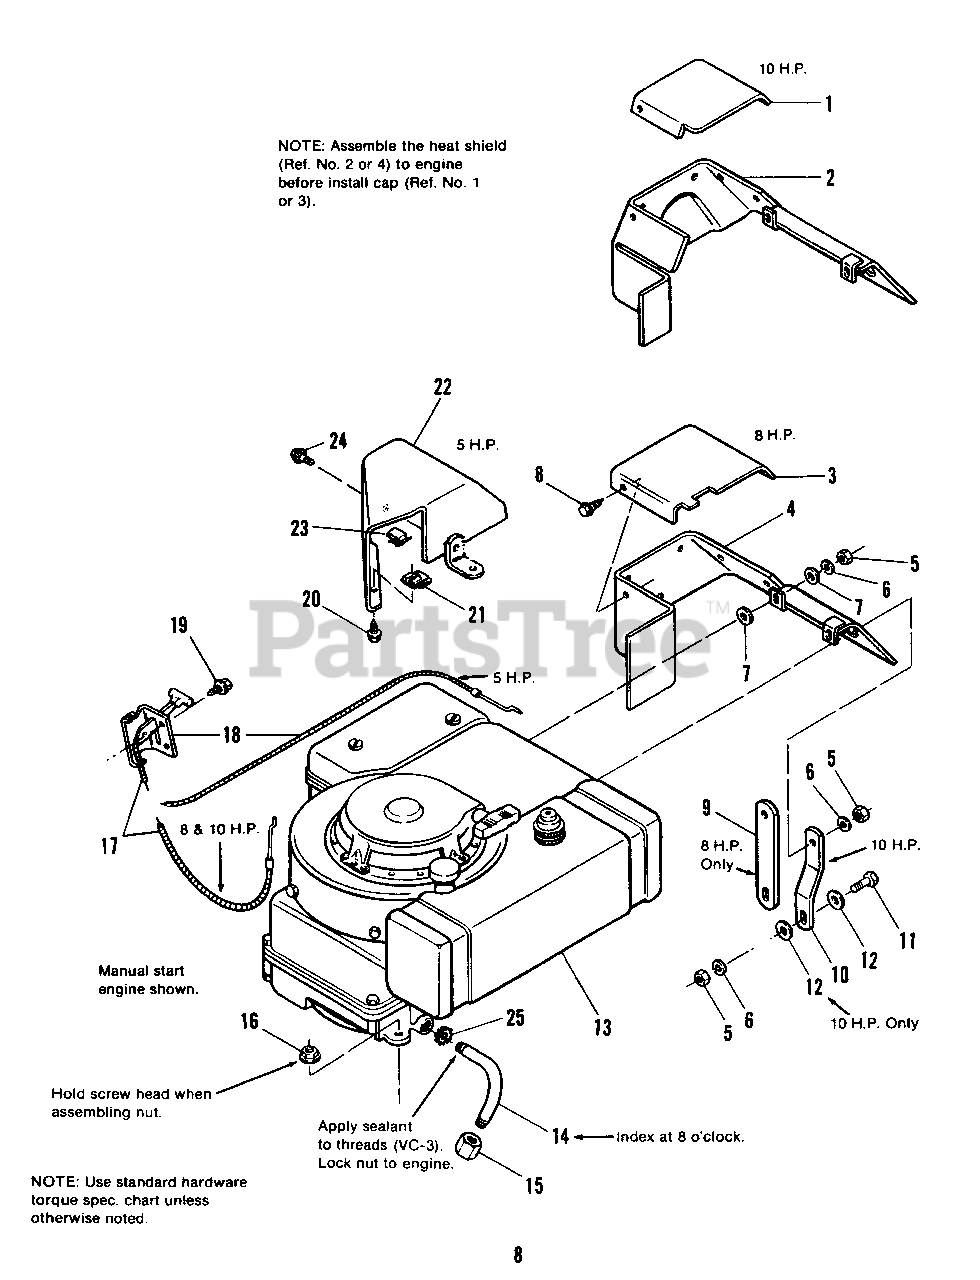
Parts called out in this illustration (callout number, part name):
1	CAP, Heat Shield (10 HP Only)
2	SHIELD ASSY., Heat (10 HP Only)
3	CAP, Heat Shield (8 HP Only)
4	SHIELD ASSY., Heat (8 HP Only)
5	NUT, Hex, 5/16-18 (8 & 10 HP Only)
6	LOCKWASHER, 5/16-18 (8 & 10 HP Only)
7	WASHER, Plain, 5/16 (8 & 10 HP Only)
8	SCREW, Hex,Thd. Forming, #10 x 3/8 (8 & 10 HP Only)
9	STRAP, Cylinder Head (8 HP Only)
10	STRAP, Cylinder Head (10 HP Only)
11	CAPSCREW, Hex, 5/16-18 x 1-1/2 (8 & 10 HP Only)
12	WASHER, Plain, 5/16 (8 HP- qty. 1)
13	ENGINE, 5 HP Man. Start
13	ENGINE, 8 HP Man. Start
13	ENGINE, 8 HP Elec. Start
13	ENGINE, 10 HP Elec. Start
14	DRAIN, Oil
16	LOCKNUT, Whiz, 3/8-16 (5 HP Only)
17	CONTROL, Throttle (8 & 10 HP Only)
18	CONTROL, Throttle (5 HP Only)
19	SCREW, Hex, Taptite, 1/4-20 x 3/8
20	SCREW, Hex, Taptite, #10 x 1/2
21	U-NUT, #10 (5 HP Only)
22	SHIELD, Heat (5 HP Only)
23	CLIP (5 HP Only)
24	CAPSCREW, Hex Hd., Taptite, 5/16-18 x 3/8
25	LOCKNUT, Conduit, 3/8
